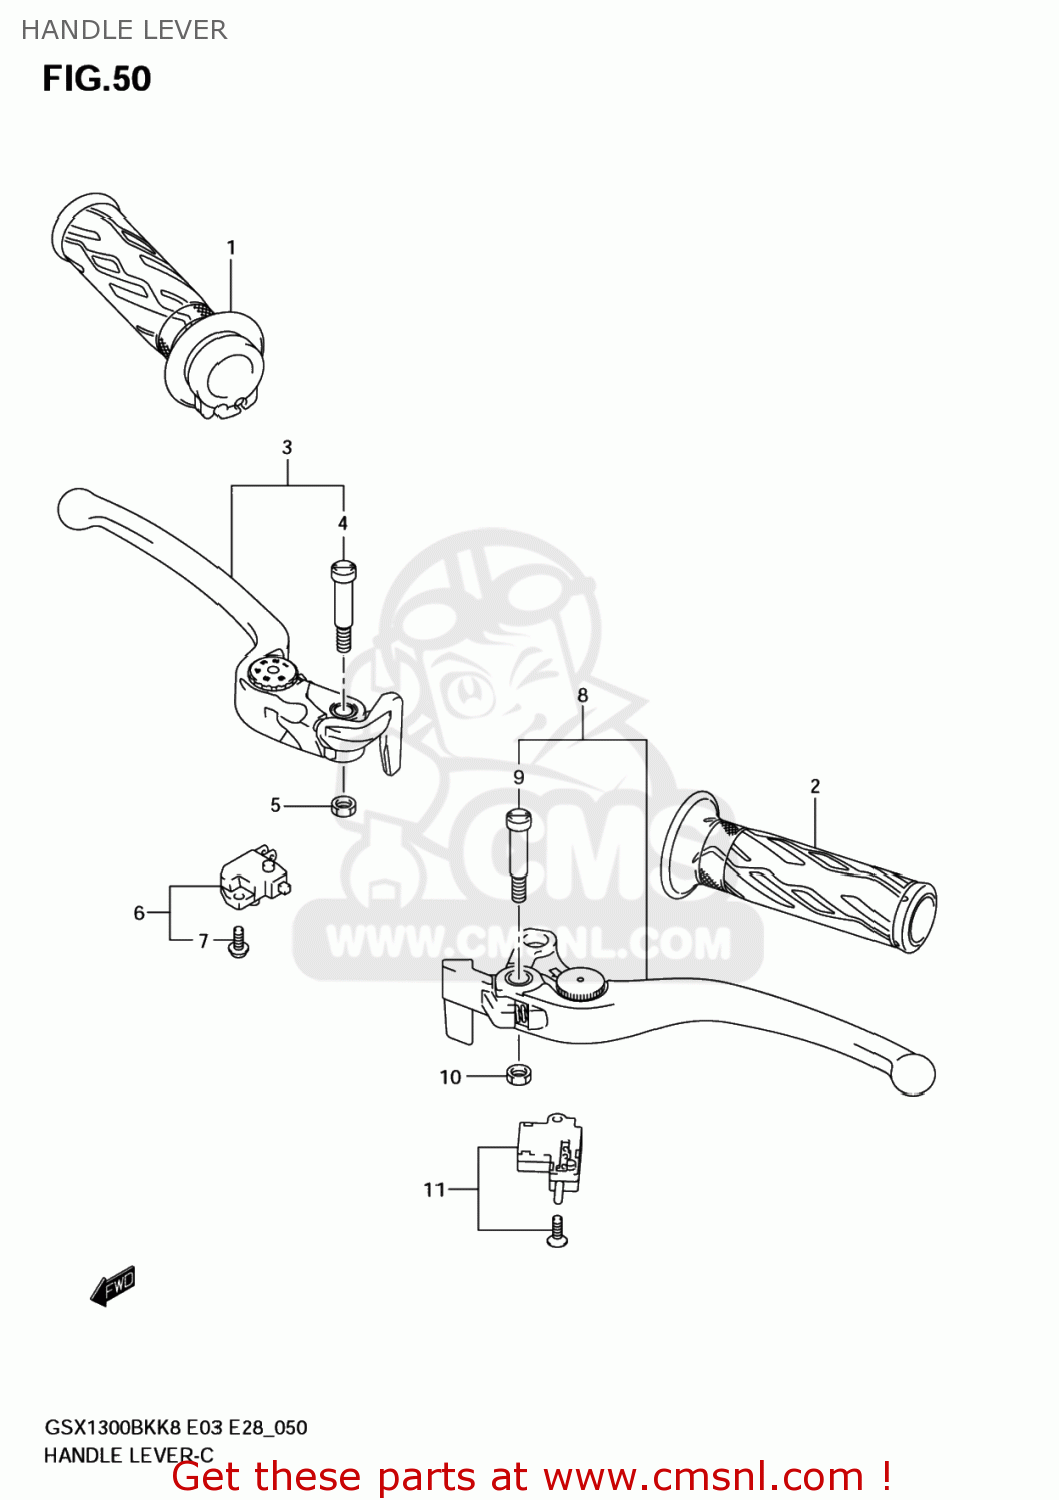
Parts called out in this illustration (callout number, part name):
1	GRIP COMP,THRO
2	GRIP,L
3	LEVER ASSY,BRA
4	BOLT,LEVER PIVOT
5	NUT,LEVER PIVOT
6	SWITCH ASSY,ST
7	SCREW
8	LEVER ASSY,CLUTCH
9	BOLT,LEVER PIVOT
10	NUT,LEVER PIVOT
11	SWITCH ASSY,CLUTCH
